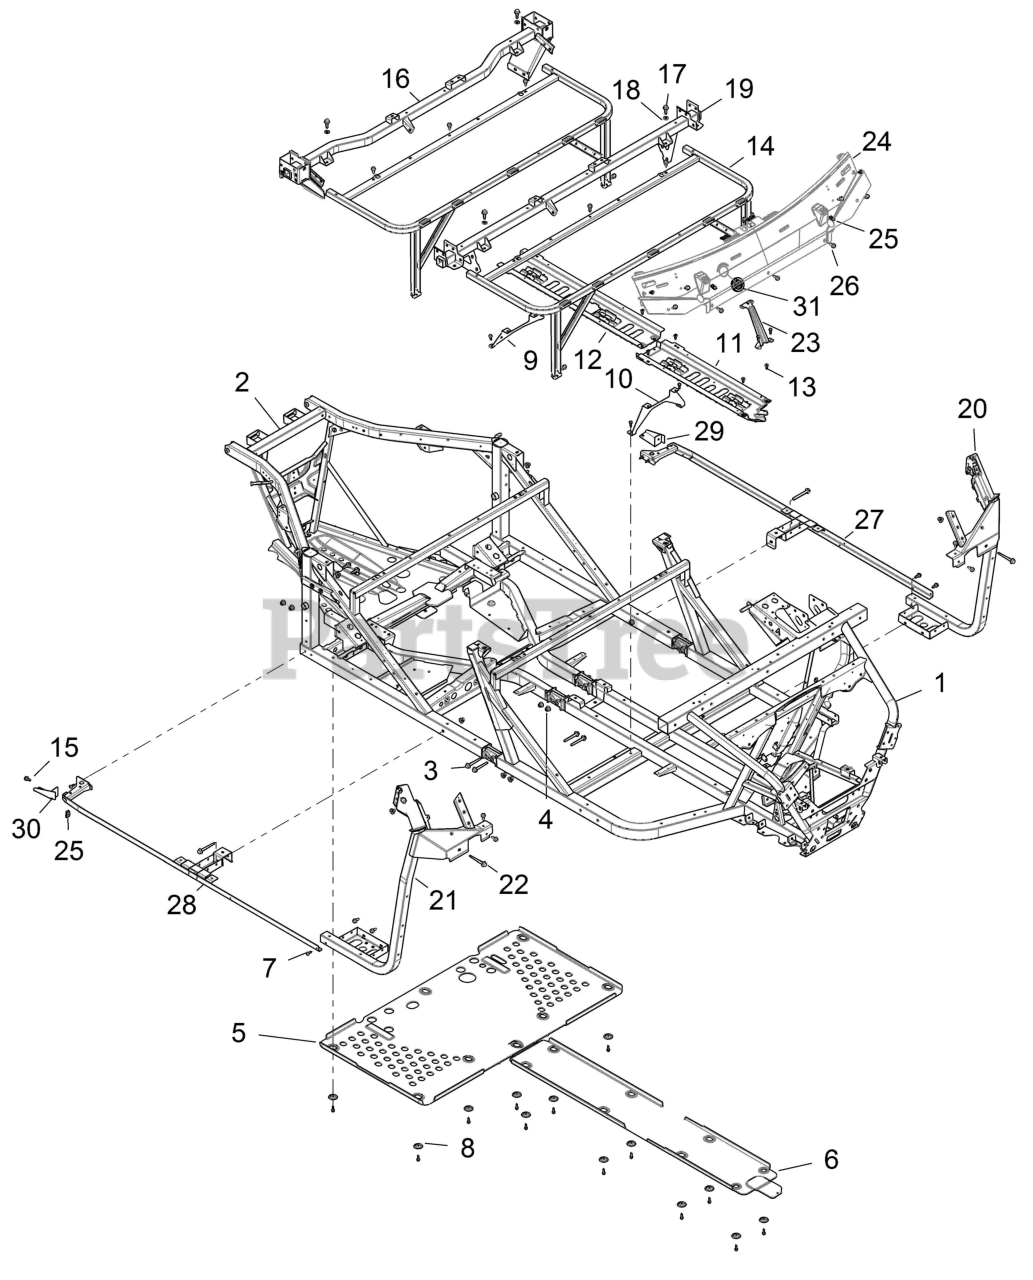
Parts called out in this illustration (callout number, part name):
1	WELD-FRAME,MAIN,FRONT,ARNS,BLK
2	WELD-FRAME,MAIN,REAR,DSL,BLK
3	BOLT-M10X1.25X70,HXFLG-OLIVE D
4	NUT-M10X1.25,FLG,NYLOC-OLIVE D
5	PLATE-SKID,REAR,BLK
6	PLATE-SKID,FRONT,BLK
7	SCR-M6X1.0X20,HXHD,FLG,TDFM,BL
8	WASHER SKID PLATE
9	BRKT-ROUTING TRAY,BLK
10	BRKT-ROUTING TRAY CTR,BLK
11	TRAY-ROUTING,BLK
12	TRAY-ROUTING,REAR,BLK
13	RIVET-TUFLOK,.315-.325X.787 (5
14	WELD-CAB/SEAT BASE,BLK
15	SCR-TXTH-M6X1.0X25 RIE
16	WELD-CAB SUPPORT,REAR,BLK
17	SCR-HXFL-M10X1.25X30 8.8 ZOD
18	WASHER,3/8 FW
19	SUPPORT, CAB, BLACK
20	WELD-FLOOR SUPPORT,LH,BLK
21	WELD-FLOOR SUPPORT,RH,BLK
22	SCR-HXFL-M10X1.25X80 8.8 ZOD
23	BRKT-PLATE,CTR,PIN MT,TTN
24	PLATE,WINDSHIELD MOUNT,LOW BLK
25	CLIP-U SPEED NUT
26	BOLT-M8X1.25X20,HXFLG,TAP/R-OD
27	WELD-ROCKER,LH,BLK
28	WELD-ROCKER,RH,BLK
29	BRACKET,SUPPORT,ROCKER,LH BLCK
30	BRACKET,SUPPORT,ROCKER,RH BLCK
31	GROMMET-ELEC,CAB,SLIT
